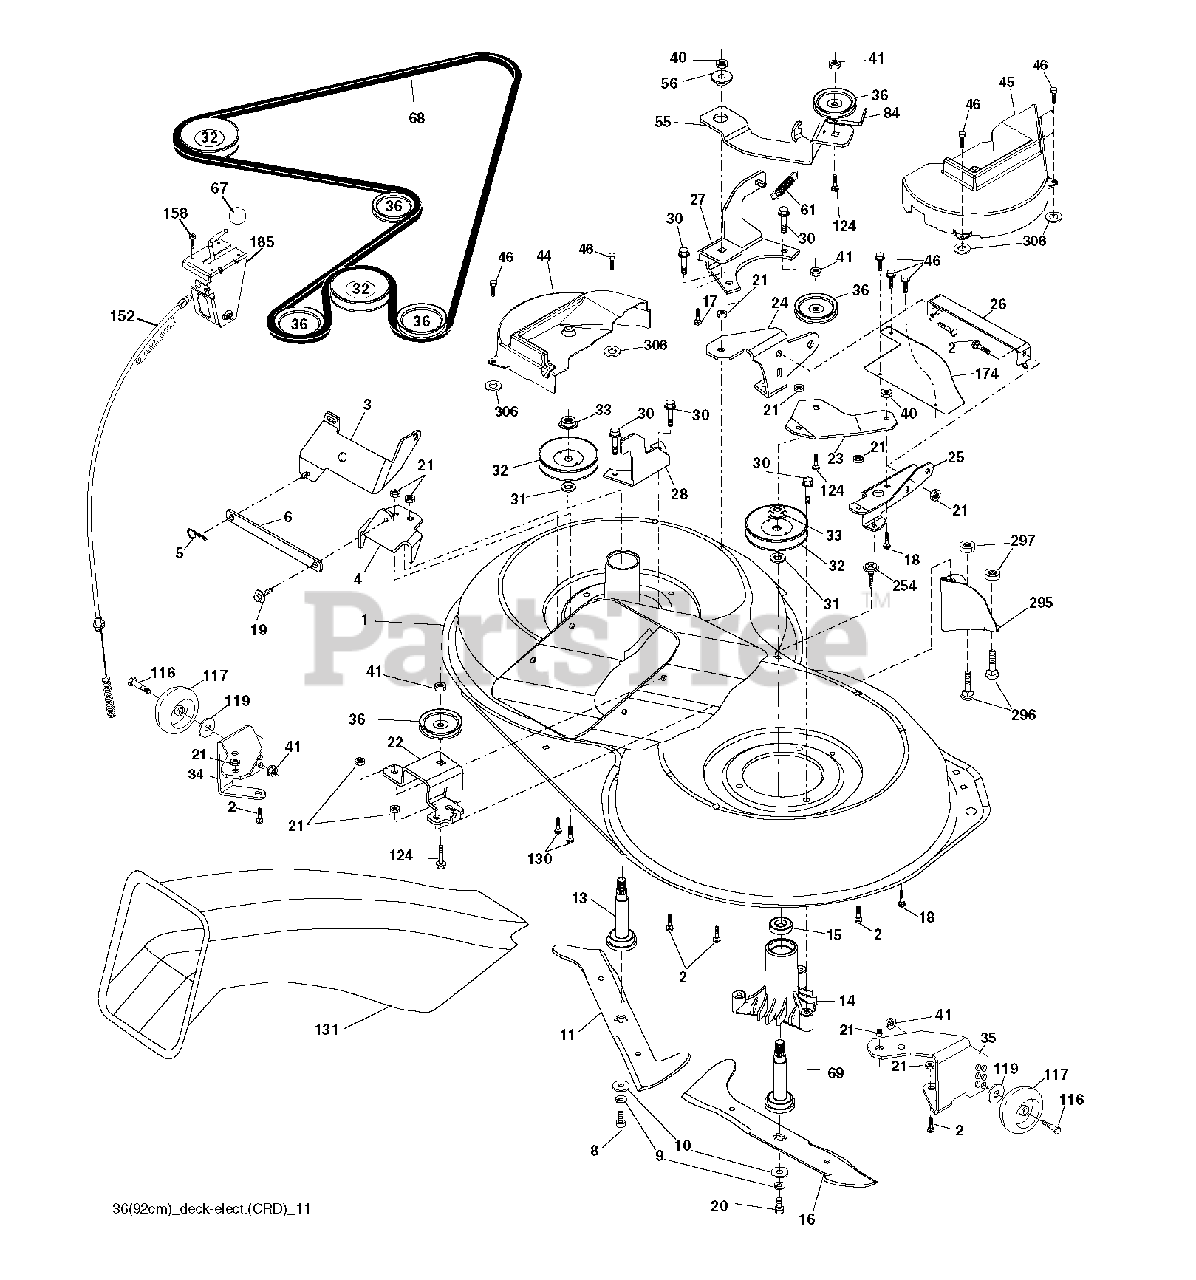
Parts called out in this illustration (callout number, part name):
2	BOLT
3	BRACKET.ASM.BAR.SWAY.CHASS
5	RETAINER-SPRNG RB
6	BAR SWAY
9	LOCKWASHER
10	WASHER.BLADE
13	SHAFT ASM VENT
14	HSG MANDREL
17	BOLT.3/8-14X1.25
19	BOLT SHD 5/16-18
21	LOCKNUT
24	BRACKET
25	BRACKET
28	BRACKET
30	SCREW, WASHER HEAD
31	WASHER.SPACER.MANDREL
32	PULLEY MANDREL
33	NUT.FLANGE.LOCK.TOP
36	PULLEY.IDLER.4.25
40	LOCKNUT
41	NUT LOCK FLG 3/8-16 UNC
46	SCREW.1/4-20X5/8
56	SPACER.RETAINER.MOWER
67	KNOB T (3/8 HOLE)
69	SHAFT.ASM.W/LWR.BRG.RH.THREAD
84	KEEPER, BELT IDLER
116	BOLT.SHOULDER.3/8-16X3-5/8
117	WHEEL. GUAGE RALLY
124	BOLT.3/8-16X1.50
131	CHUTE BAGGER
158	SCREW
185	HEAD ASM. CABLE CLUTCH
254	SCREW 3/8-16X1
296	BOLT
297	NUT CENTERLOCK
306	PALNUT 1/4
